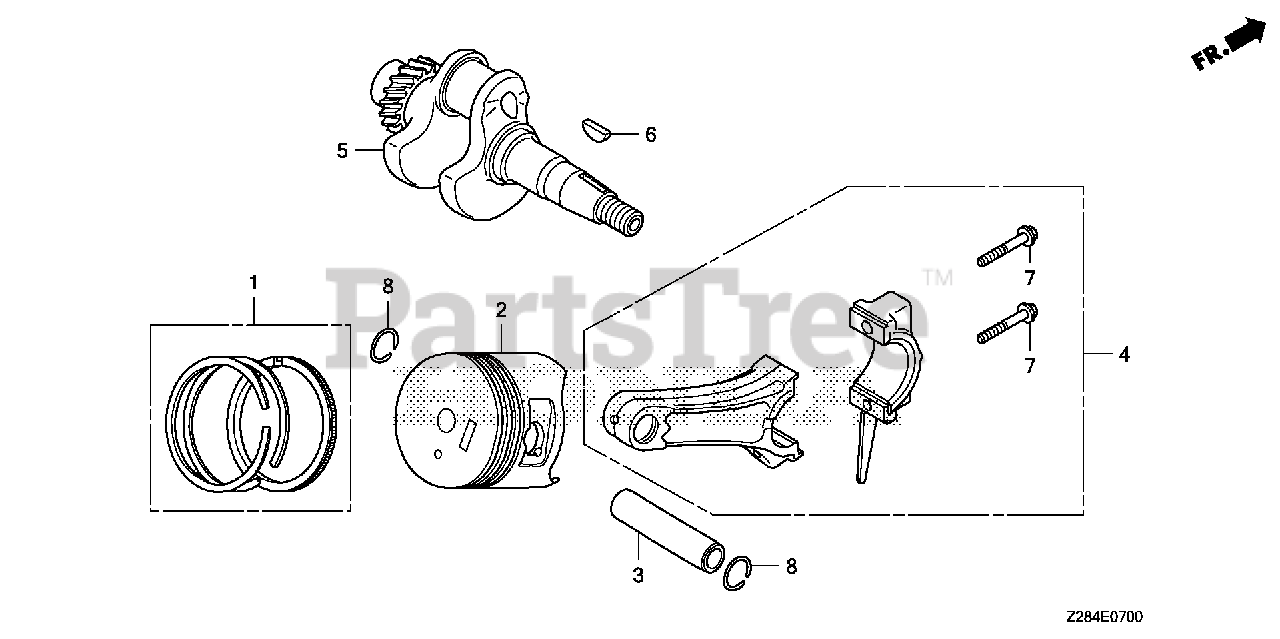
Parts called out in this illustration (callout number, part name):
1	RING SET, PISTON (0.25) (TPR)
1	RING SET, PISTON (0.50) (TPR)
1	RING SET, PISTON (STD) (RIKEN)
1	RING SET, PISTON (0.25) (RIKEN)
1	RING SET, PISTON (0.50) (RIKEN)
2	PISTON (STD)
2	PISTON (0.25)
2	PISTON (0.50)
3	PIN, PISTON
4	ROD ASSY., CONNECTING
4	ROD ASSY., CONNECTING (UNDER SIZE)
5	CRANKSHAFT
6	KEY, SPECIAL WOODRUFF (25X18)
7	BOLT, CONNECTING ROD (6X34.5)
8	CLIP, PISTON PIN (18MM)
